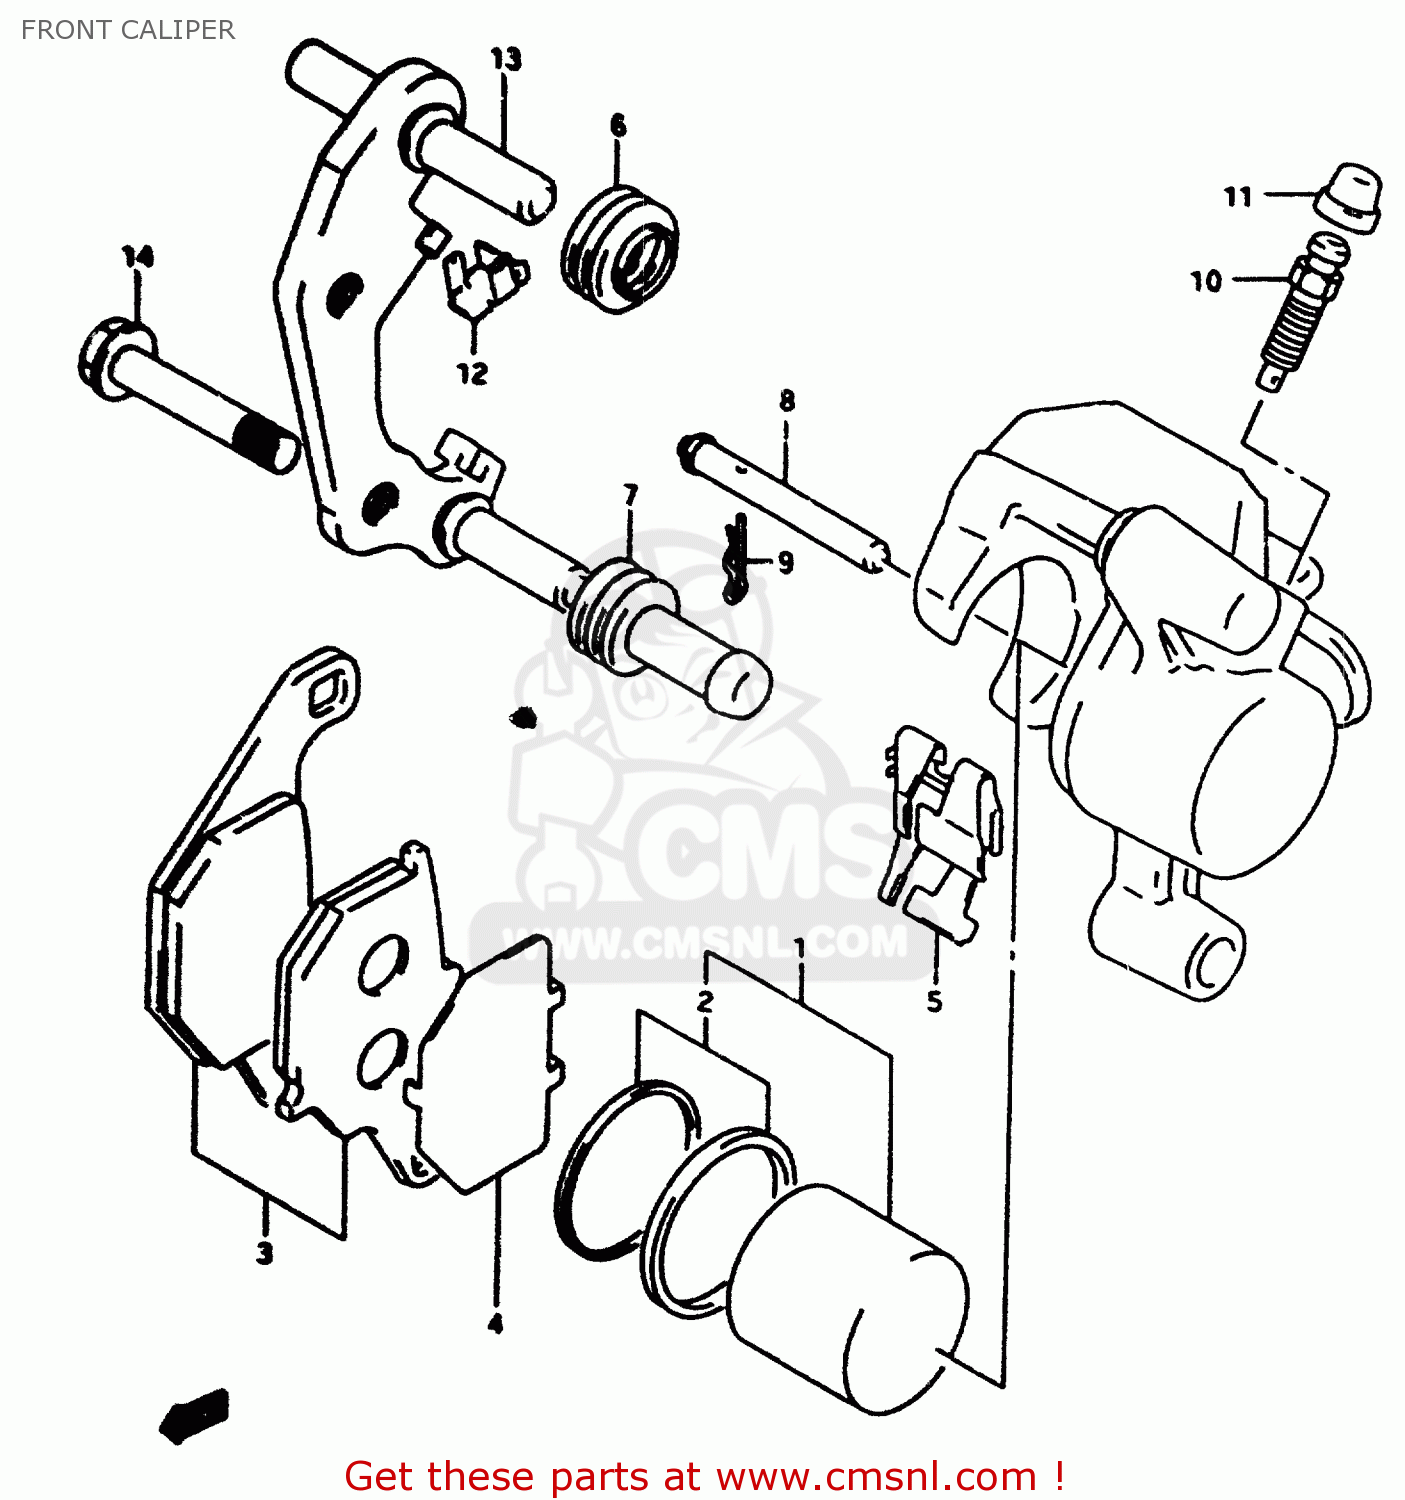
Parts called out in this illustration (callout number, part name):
1	PISTON SET
2	SEAL SET,PISTON
3	PAD SET (NAS)
4	SHIM,PAD
5	SPRING,PAD
6	BOOT,AXLE
7	INSULATOR,AXLE
8	PIN,PAD
9	CLIP,PAD PIN
10	BLEEDER
11	CAP,BLEEDER PLUG
12	GUIDE,PAD
13	CARRIER,CALIPER,L
14	BOLT(8X41)
